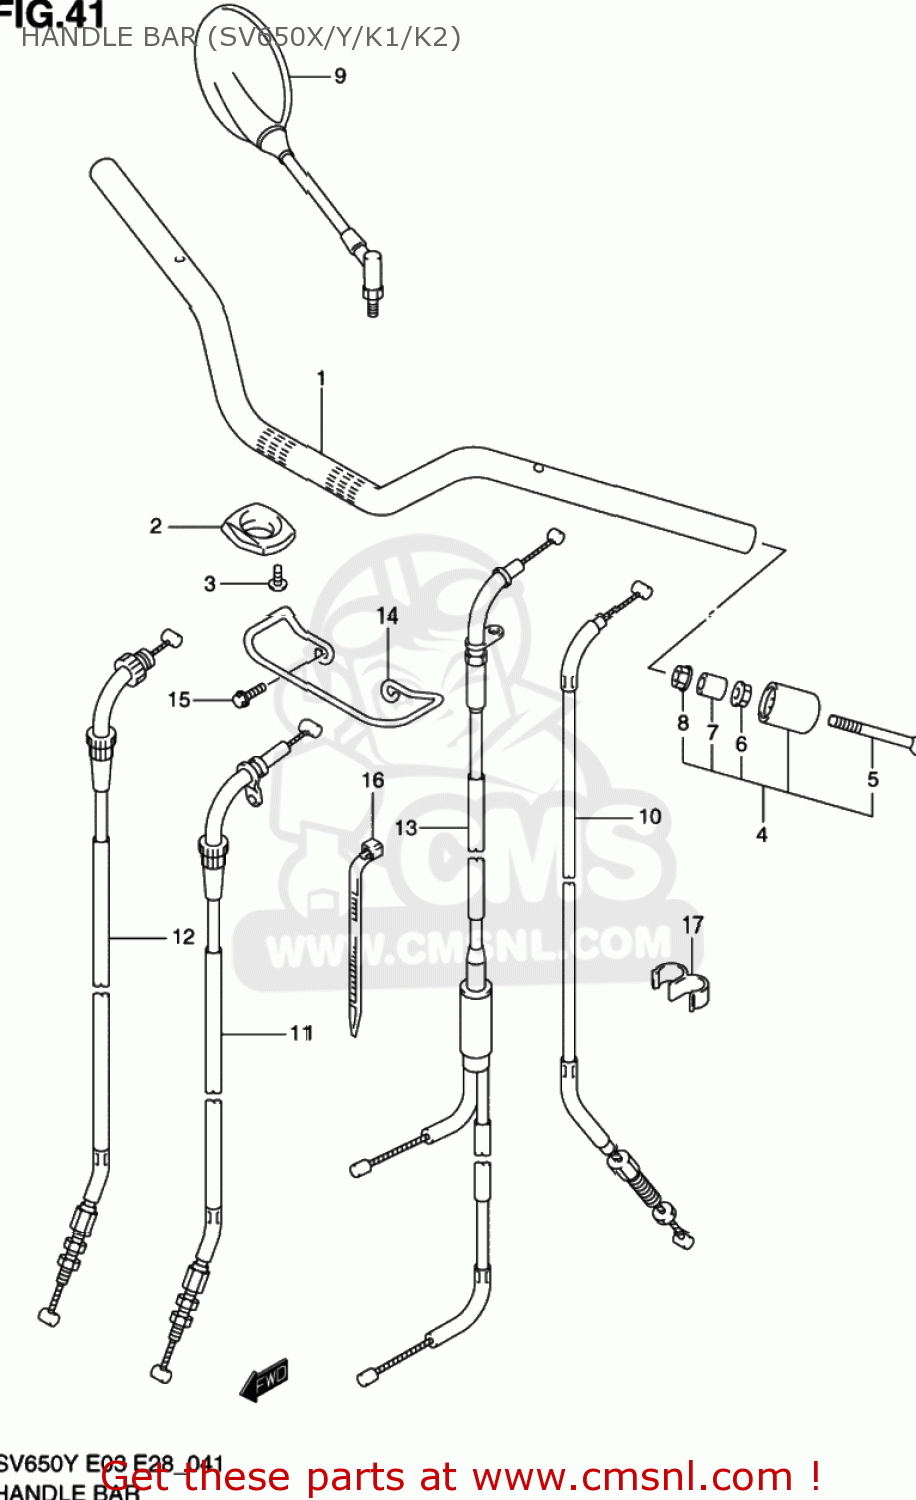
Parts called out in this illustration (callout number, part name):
1	HANDLEBAR
2	COVER,IGNITION SWITCH
3	SCREW
4	BALANCER SET,HANDLEBAR
5	SCREW
6	NUT
7	EXPANDER,HANDLE BALANCER
8	NUT
9	MIRROR ASSEMBLY,RIGHT
10	CABLE ASSY,CLUTCH
11	CABLE ASSY,THROTTLE NO.1
12	CABLE ASSY,THROTTLE NO.2
13	CABLE,STARTER
14	GUIDE,CABLE
15	BOLT
16	CLAMP(L:145)
17	CLAMP
